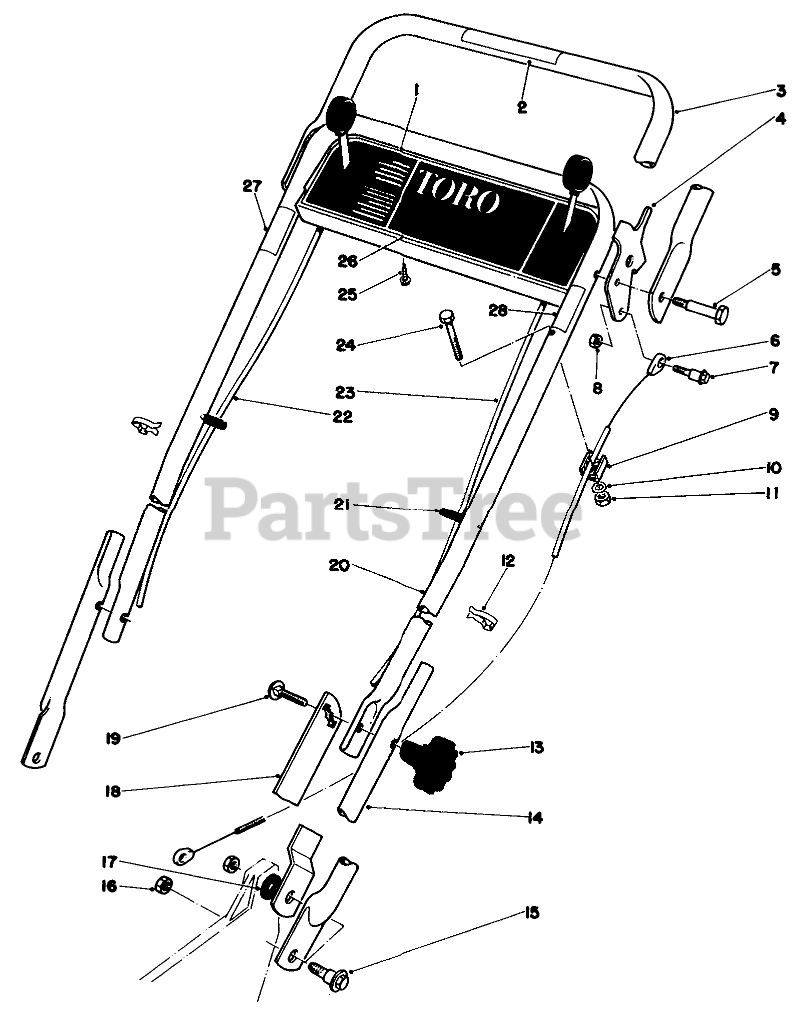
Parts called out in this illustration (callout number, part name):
1	Control Panel
2	Decal-Traction Handle (French & Dutch)
3	Demand Handle
4	Demand Handle Stop
5	BOLT-SHOULDER
6	DEMAND HANDLE CABLE
7	Shoulder Bolt
8	NUT-HEX, SIDE DEFORM
9	CLAMP-CABLE
10	WASHER-FLAT
11	NUT-LOCK, NI
12	BOWDEN CLIP
14	LOWER HANDLE
15	SCREW-SHOULDER
16	Nut
17	SPACER
18	Handle Latch L.H.
19	SCREW-CARR
20	Upper Handle
21	CAP-VINYL
22	GROUND SPEED CONTROL
23	Throttle Control
24	SCREW-HH
25	SCREW-HWHTF
26	Decal-Control Panel
27	Decal-Control Shift (French & Dutch)
28	Decal Throttle Control
